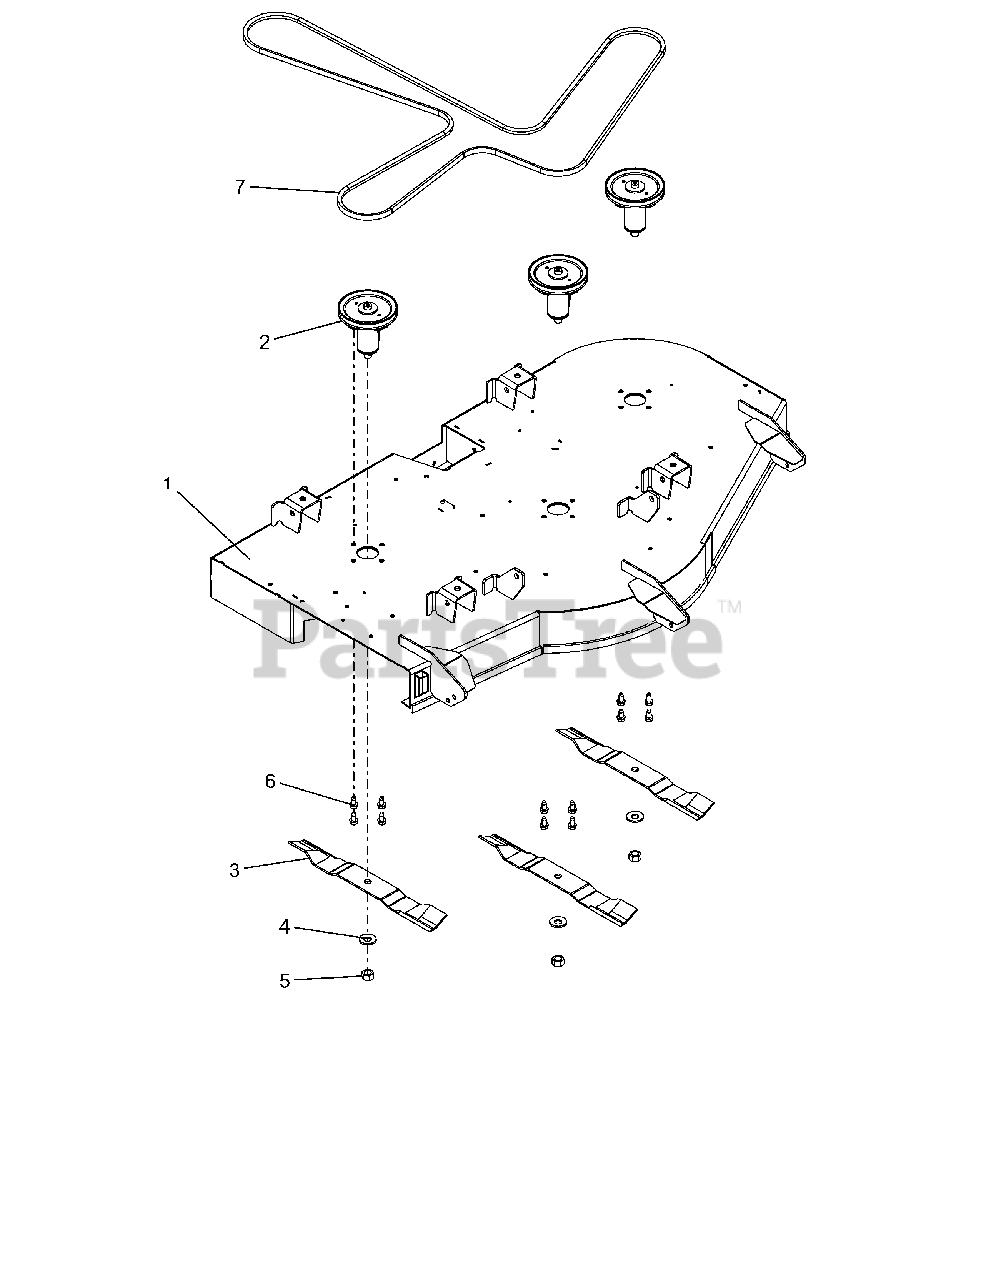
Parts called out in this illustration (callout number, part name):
1	KIT, 52" GRAVELY DECK W/DECALS
2	KIT, DECK SPINDLE ASM-52
3	BLADE, 18" - 30 DEG .5 OFFSET
4	WSHR-BLVL .669X1.535X.138
5	NUT-STD .625-18 ZCC
6	SCR,TAP .375-16X.75 HWH TR ZCC
7	V-BELT, HA-WRAPPED
